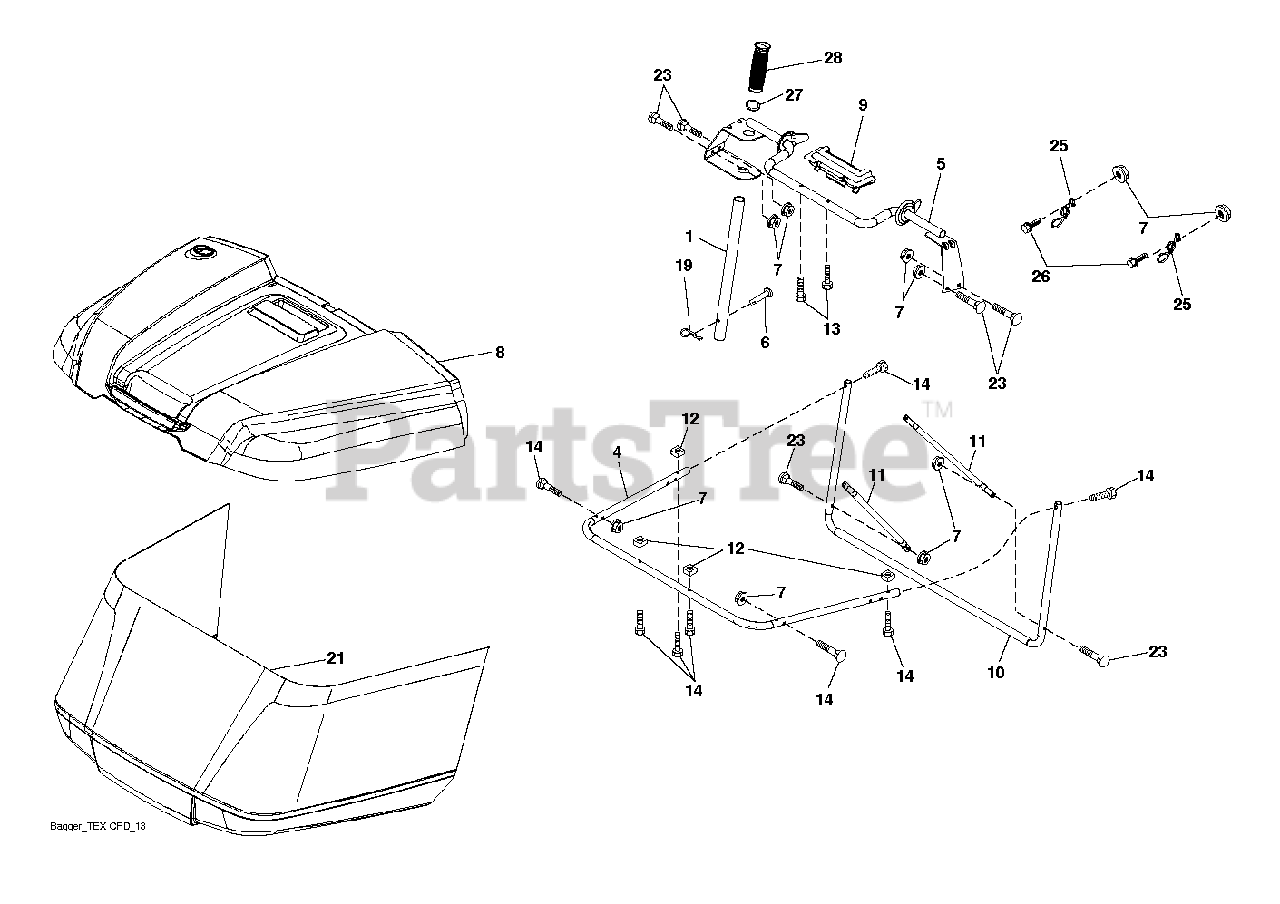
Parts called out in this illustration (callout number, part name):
1	TUBE.PNT.HDL.BAGGER.
6	RIVET,DRILLED
7	NUT T
19	PIN.COTTER.5/16.BOW TI
26	SCREW HEX CRT
28	GRIP.HANDLE.BLACK
